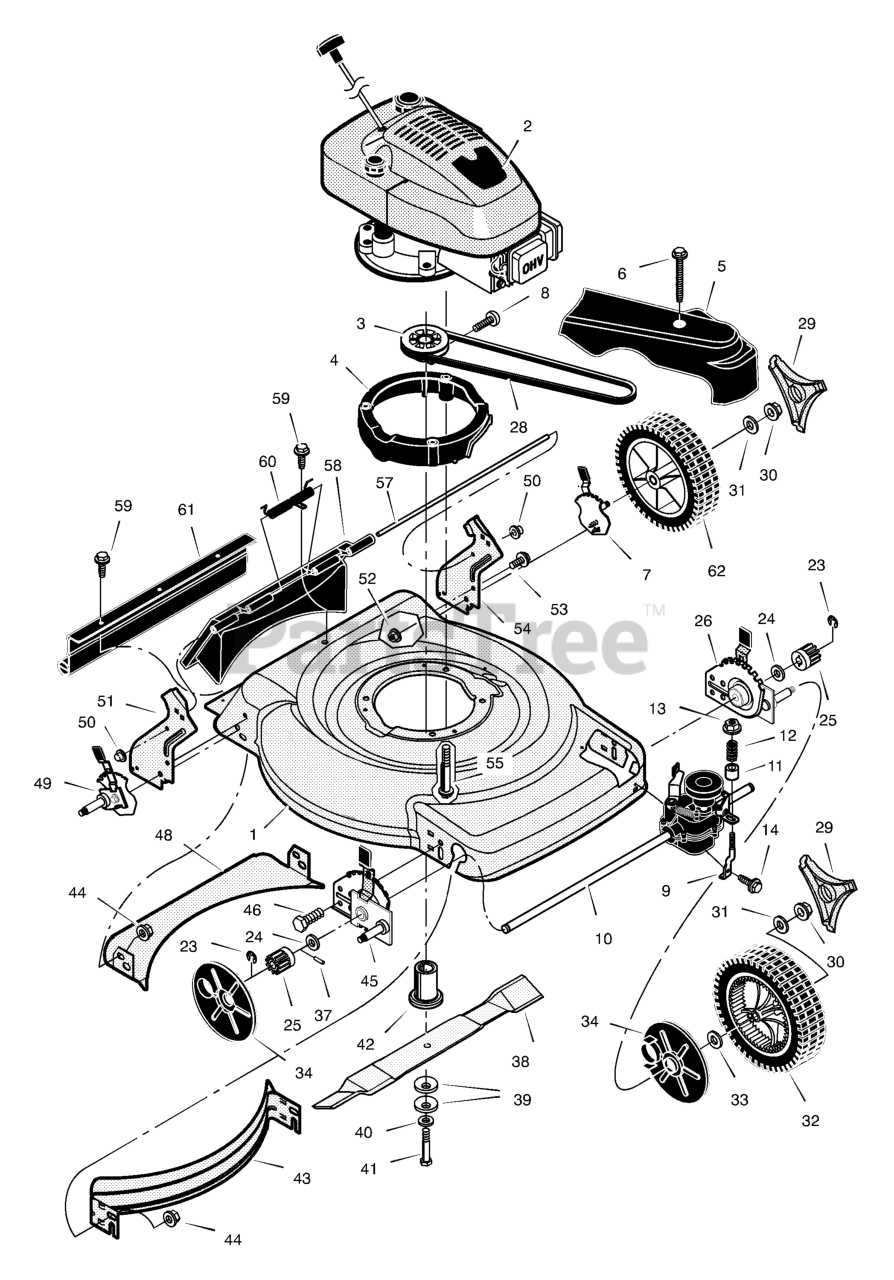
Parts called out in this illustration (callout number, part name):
1	Housing
2	Engine
3	Pulley, Drive
4	Spacer, Engine
5	Cover, Belt (Gray)
7	Adjuster, Left Rear Height
9	Support, Spring
10	Transmission *
12	Spring, Compression
13	Nut
25	Gear, Pinion
26	Adjuster, Left Front Height
29	Cap, Hub
30	Nut, Flange
31	Washer
32	Wheel & Tire, Front
34	Cover, Dust
37	Pin, Drive
39	Washer, Belleville
42	Adapter, Blade
43	Baffle, Front
44	Nut, Flange
45	Adjuster, Right Front Height
46	Bolt
48	Baffle, Rear
49	Adjuster, Right Rear Height
50	Push On Cap
51	Bracket, Right Handle
52	Nut, Flange
53	Bolt
54	Bracket, Left Handle
55	Bolt, Engine
57	Rod, Pivot
58	Door, Rear (Gray)
61	Guard, Rear
62	Wheel & Tire, Rear
